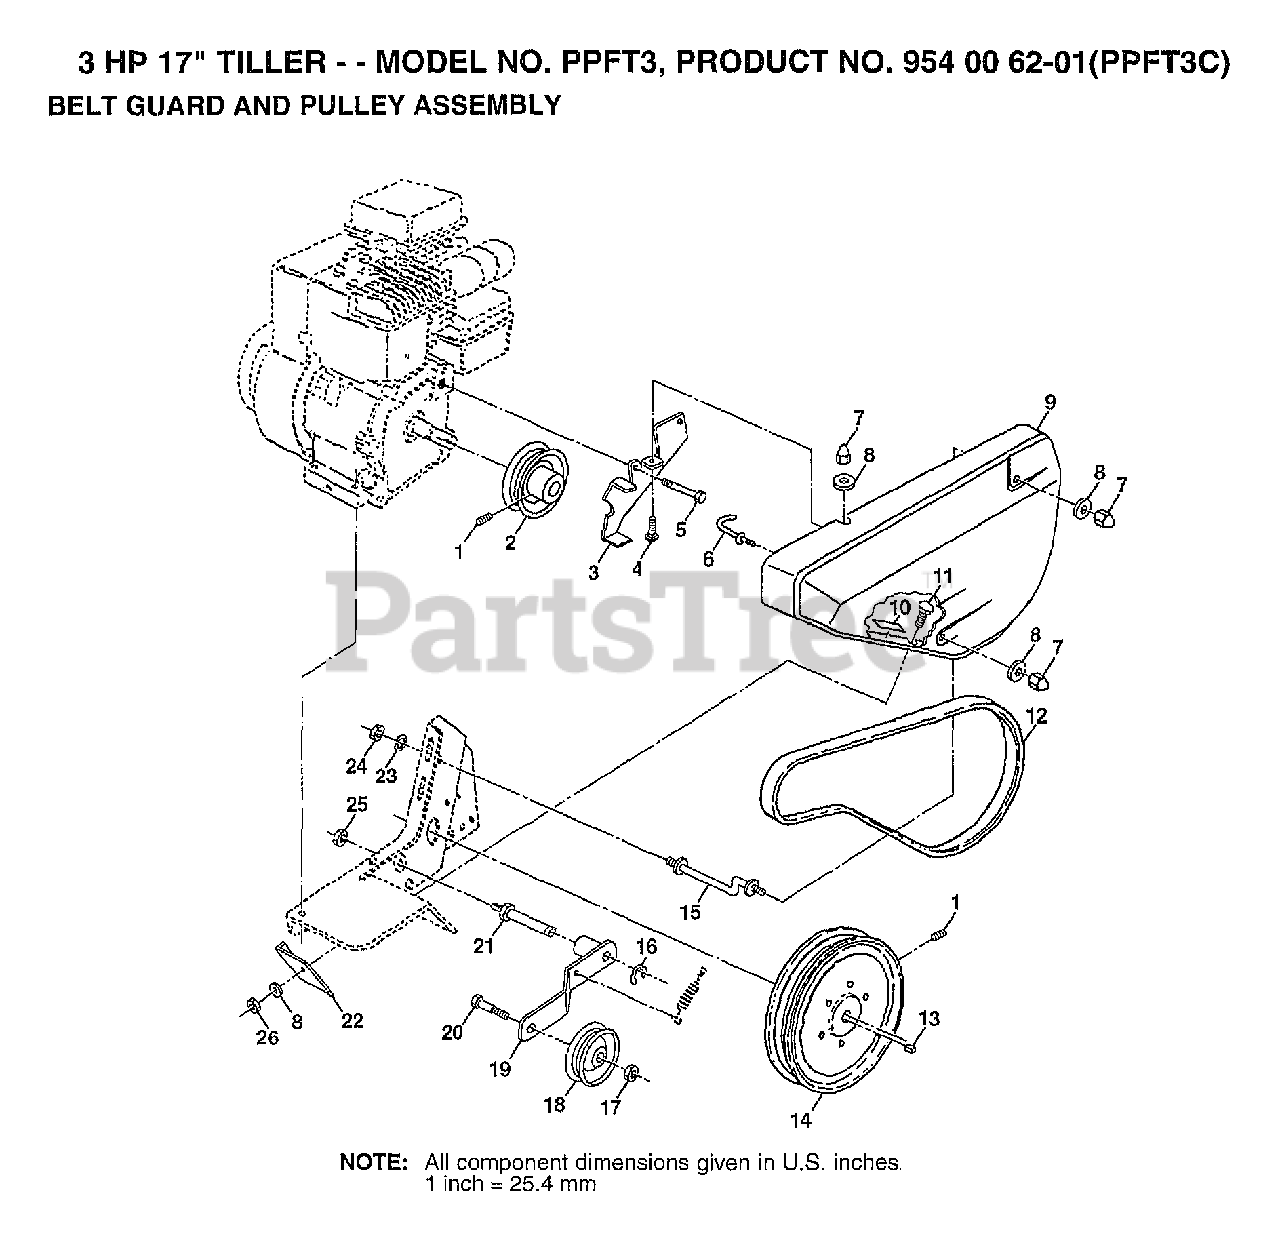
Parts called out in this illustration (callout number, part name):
1	SCREW, SET FORGED SOCKET, HEADLESS 5/16-18X3/8
2	ENGINE PULLEY
4	BOLT, CARRIAGE 1/4-20X3/4
5	BOLT, HEX 1/2-20X3/4
8	WASHER 9/32 X 5/8 X 16 GA.
11	BOLT, CARRIAGE 1/4-20 X 3/4
15	BELT GUARD BOLT
17	NUT HEX JAM 3/8-16 UNC
20	BOLT, HEX 3/8-16 X 1-1/4
23	WASHER, LOCK 1/4
24	NUT, HEX 1/4-20
25	NUT, HEX, JAM 5/16-18
26	NUT LOCK HEX W/INS 1/4-20
